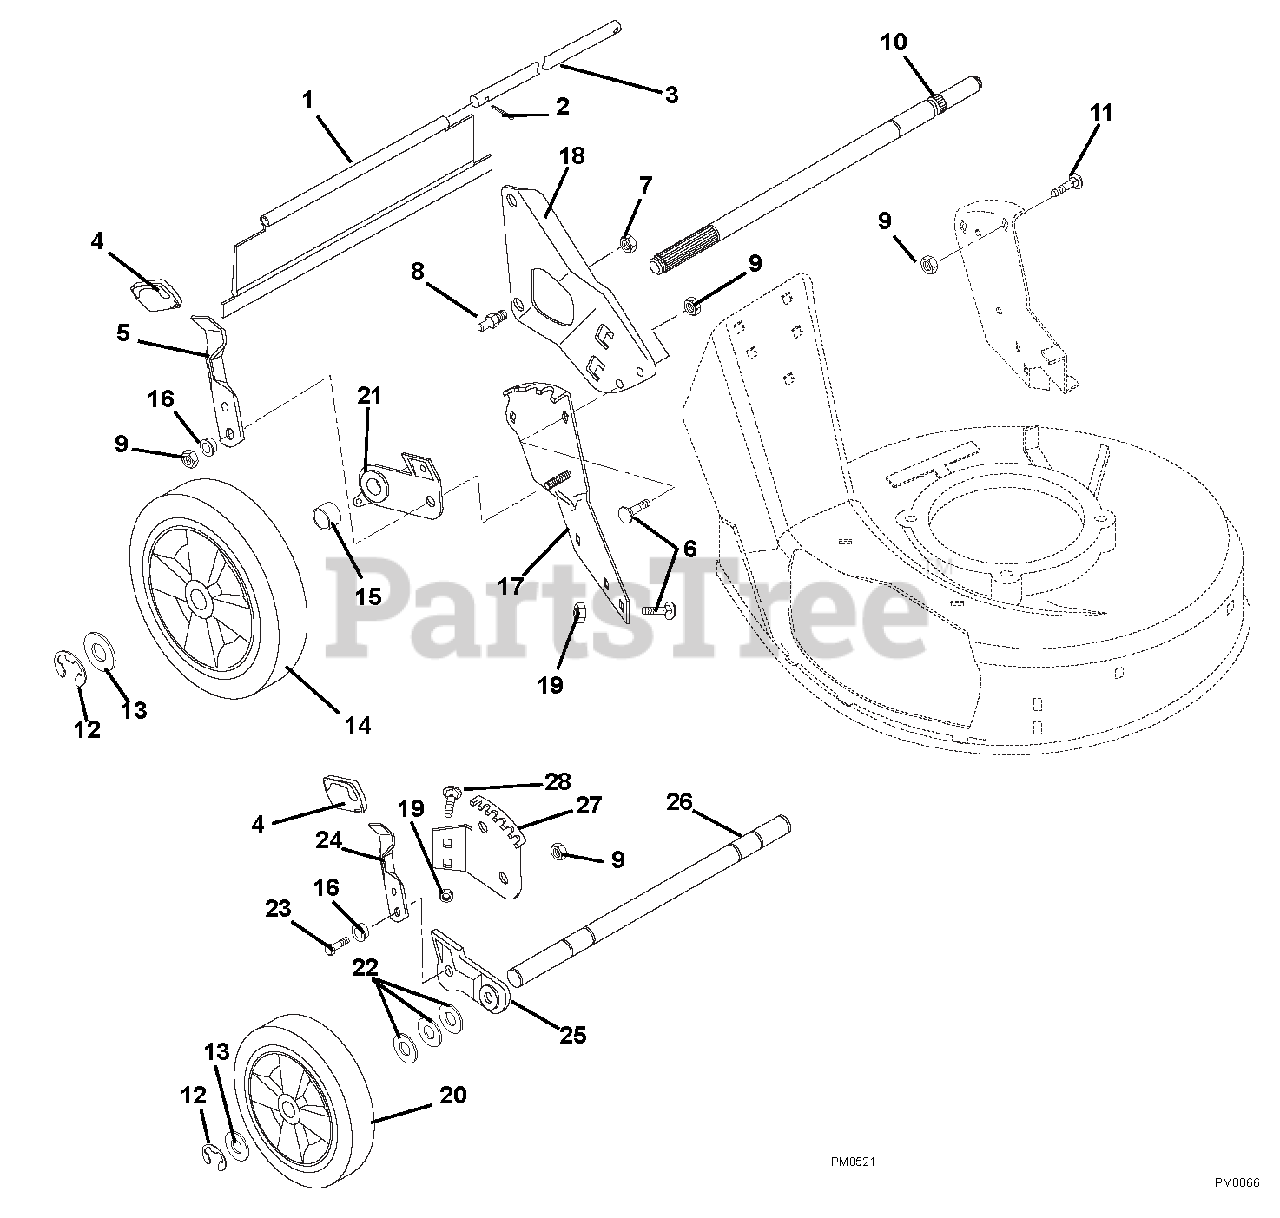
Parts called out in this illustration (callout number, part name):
1	REAR PROTECTIVE GUARD, S.P.
2	@PIN-CTR .06X.50 EXTPRSQCT YWZ
3	ROD
5	LEVER, HEIGHT ADJUSTMENT
6	@BLT-RHDSSQNK .31-18X.62 G5YZ
7	@NUT-LK-CTR .38-16 YWZC
8	HANDLEBAR STUD
9	@NUT-LK-TOP-FLG .31-18 YWZC
10	REAR AXLE,5/8 DIA
11	BLT-RDHDSQNK .31-18X1.0 SHTYZ
12	RG-RTNG-EXT .500X.042 (E)
13	WSHR-FL-STL .505X.880X.072 YWZ
14	WHL, LH 10.50"
14	WHL, RH 10.50"
14	10 1/2 TIRE SKIN
15	SPACER TUBE, SELF PROPEL
16	BSHG-FLG .32X.500X.344X.880
17	QUADRANT, REAR LH
17	QUADRANT, REAR RH
18	RH HANDLEBAR MTG. BRKT
18	LH HANDLEBAR MTG. BRKT
19	@NUT-LK-TOP-FLG .31-18 YWZC
20	WHL 7.50" .50 BORE, 1.50 HUB
21	REAR ADJUSTMENT BRACKET L.H.
21	REAR BRACKET & BEARING ASSY RH
21	REAR ADJUSTMENT BRACKET R.H.
22	WSHR-FL-STL .52X.827X.062 YWZC
23	@BLT-HEX .31-18X1.00 GR5 YWZC
24	FRONT HEIGHT ADJUSTMENT LEVER
25	LEFT ADJUSTOR BRACKET ASSEMBLY
25	RIGHT ADJUSTOR BRACKET ASSEMBL
26	FRONT AXLE
27	FRONT QUADRANT, LH
27	FRONT QUADRANT, RH
28	@BLT-RDHDSQNK .31-18X.50 G5YZ
